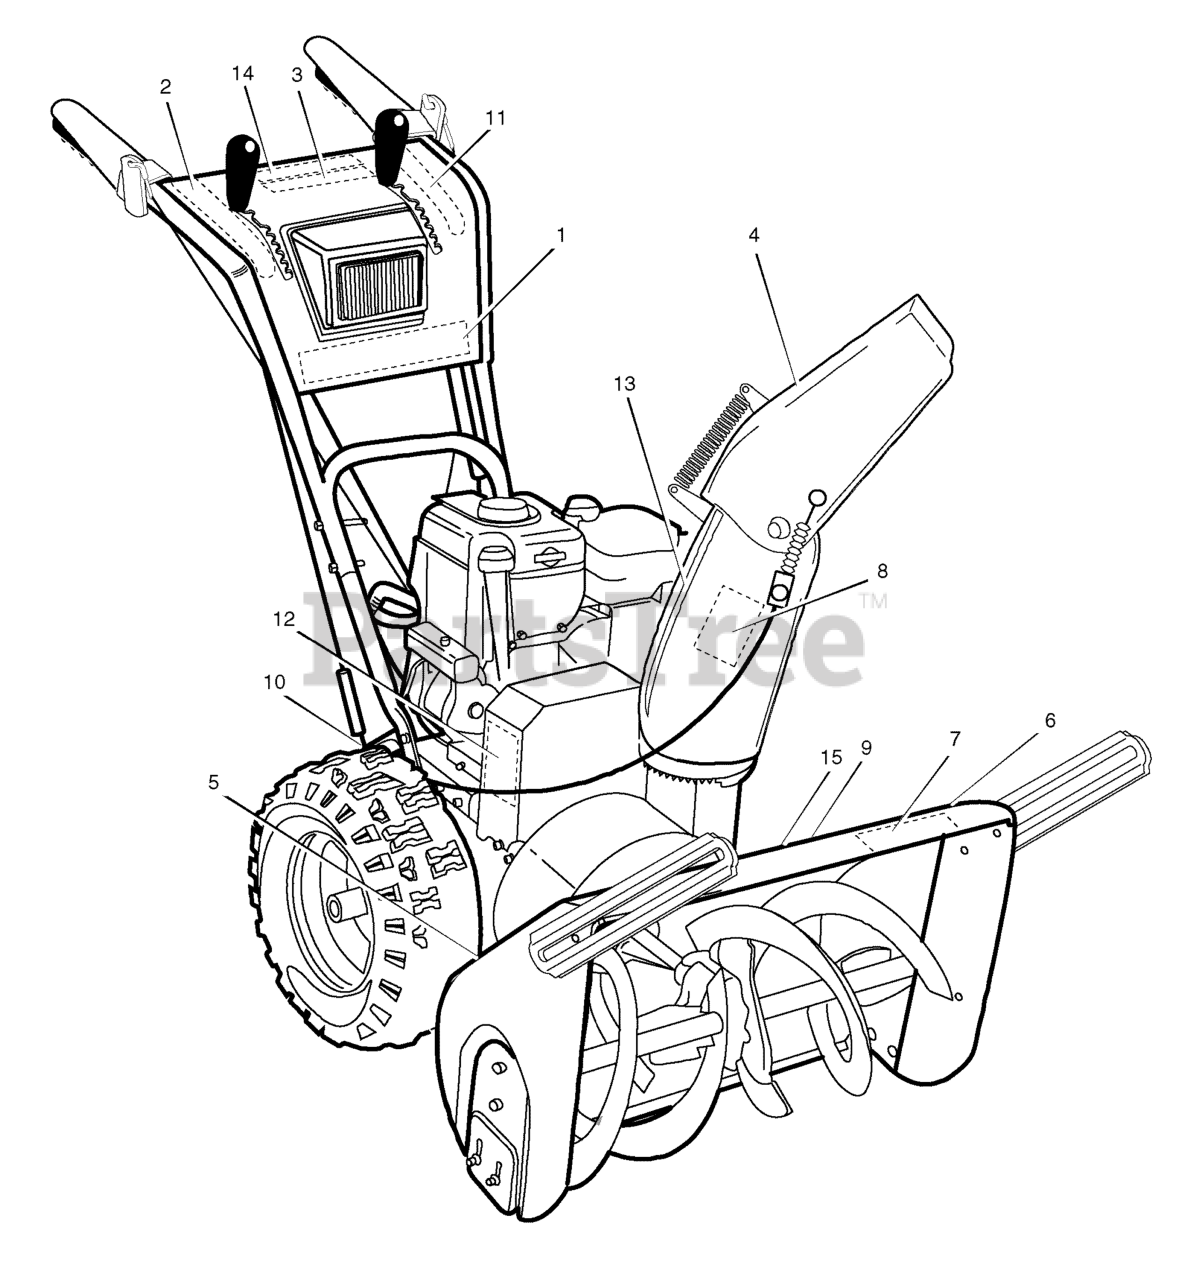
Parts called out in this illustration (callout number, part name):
1	DECAL, PANEL, MURRAY PRO
2	DECAL, SPEED PANEL
3	DECAL, TRACTION, AUGER
4	DECAL, THROWN OBJECTS
5	DECAL, DANGER FOOT
6	DECAL, FACE HEAD PHONES
7	DECAL, MURRAY PRO AUGER
8	DECAL, POWER 2 STEER ENGLISH
8	DECAL, POWER 2 STEER FRENCH
9	DECAL, 104db CE
10	DECAL, ID PLATE
11	DECAL, REMOTE CHUTE
12	DECAL, OVER ADJUSTMENT OF DISC
13	DECAL, DANGER CHUTE
14	DECAL, SINGLE HAND CONTROL
15	DECAL, CLEAN-CLEAR BRUSH FR/EN
